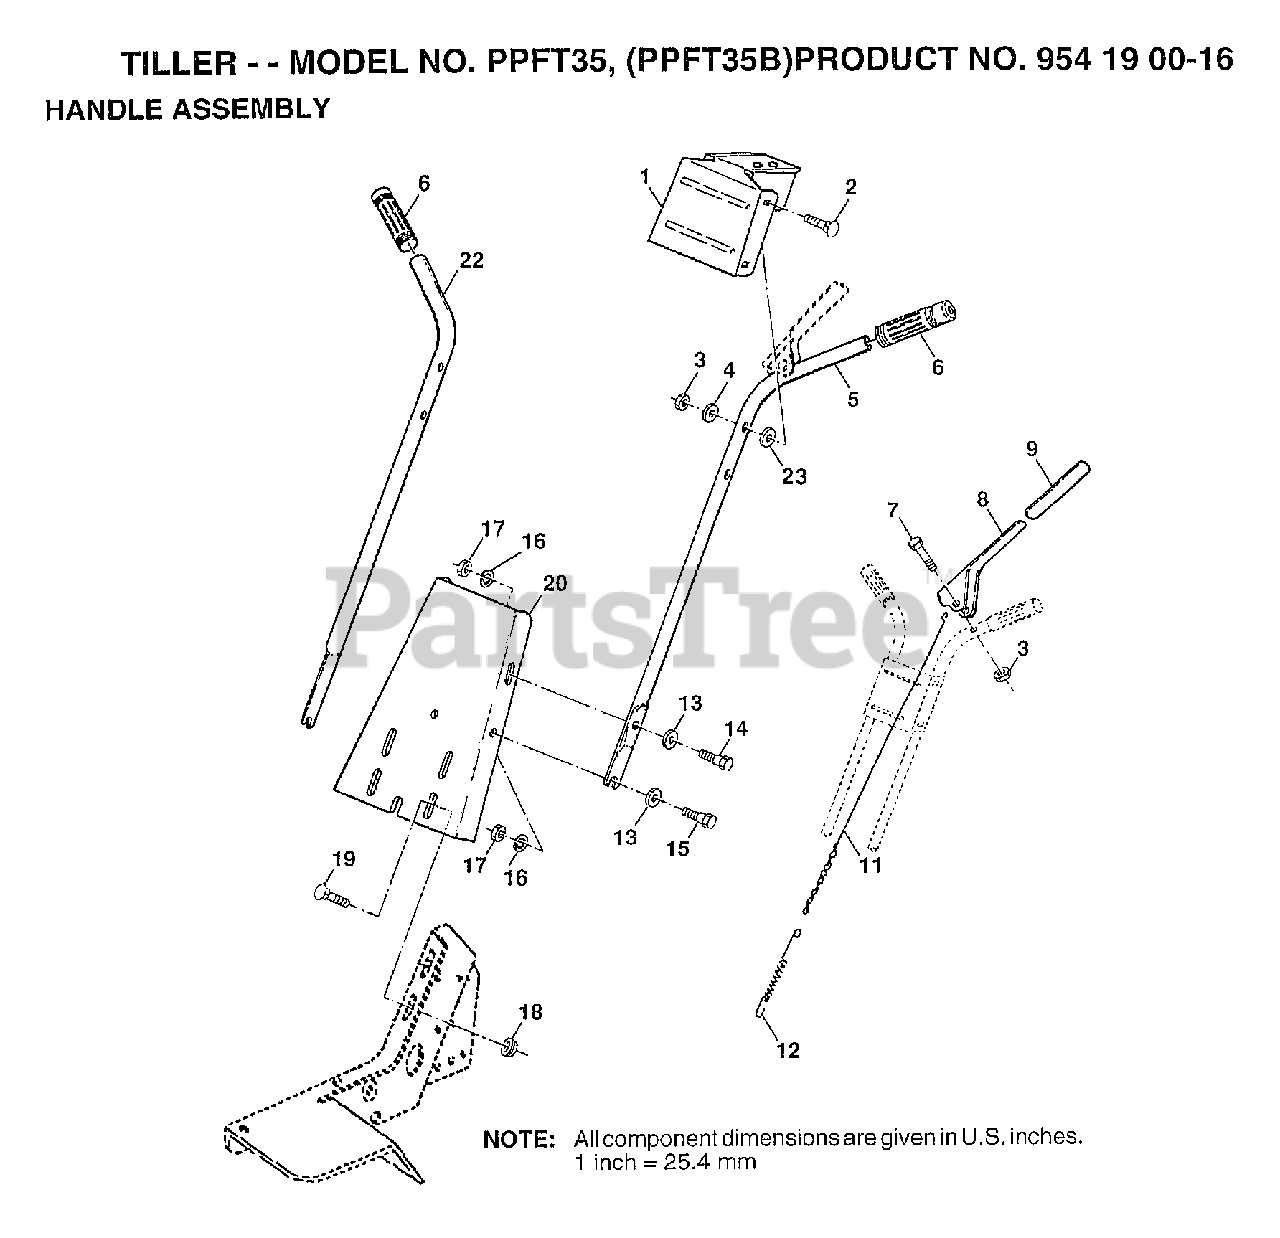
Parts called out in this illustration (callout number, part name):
1	HANDLE BRKT
2	BOLT
4	WASHER
5	HANDLE LH
7	BOLT.HEX.5/16-1.5
9	GRIP T
12	SPRING EXT TI
13	WASHER
15	BOLT
16	LOCKWASHER
17	NUT.HEX.5/16-18
18	NUT
19	BOLT
20	PANEL. HANDLE
22	HANDLE RH
23	WASHER
